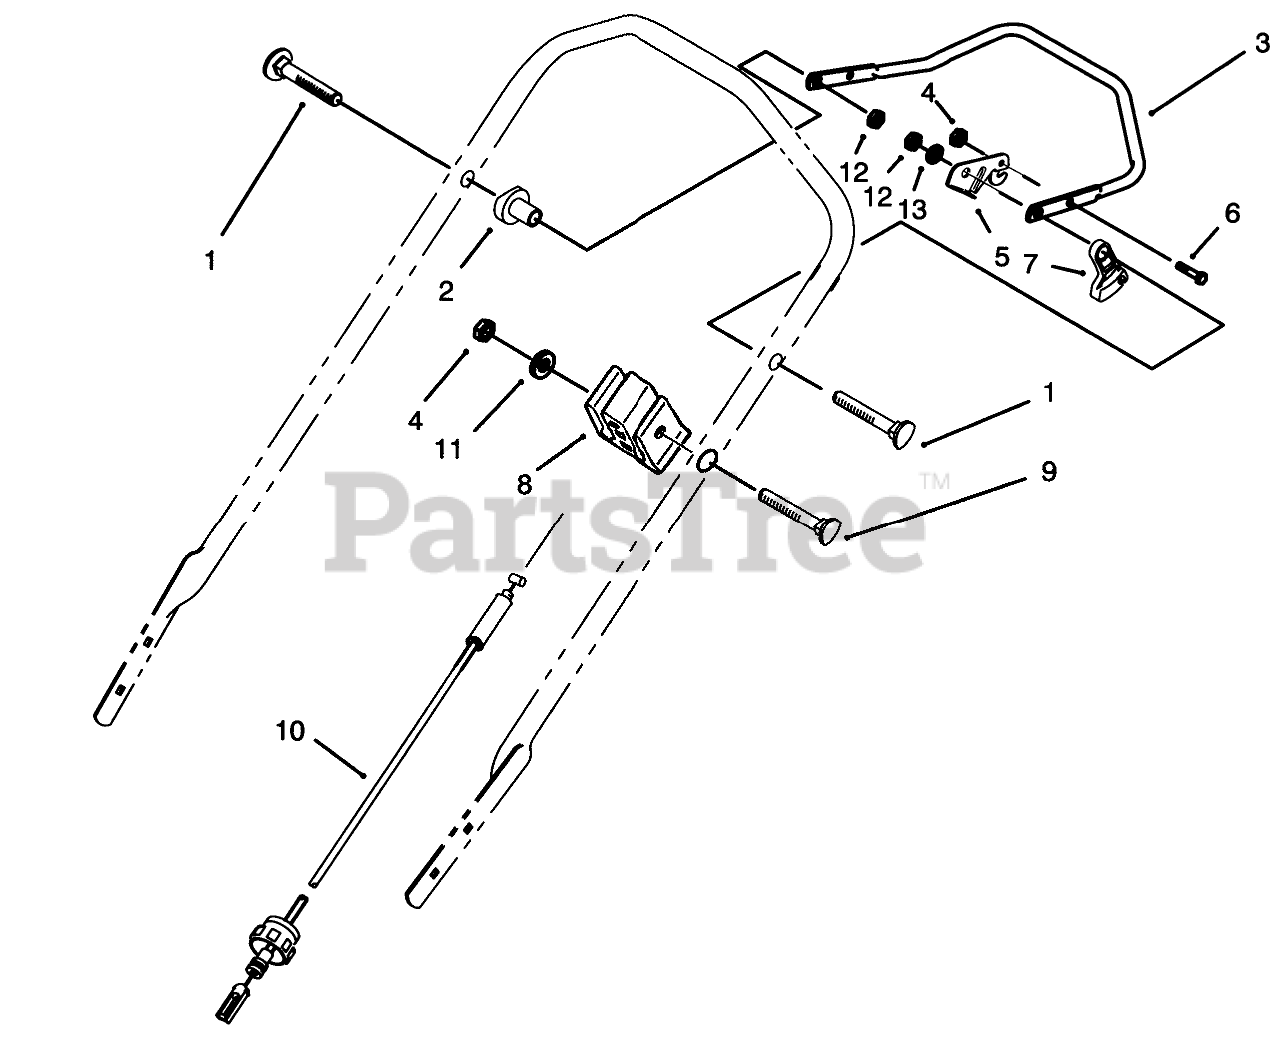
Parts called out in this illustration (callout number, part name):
1	SCREW-HANDLE
2	SPACER-SUPPORT
3	Bar-Control
4	NUT-LOCK, NI
5	CONTROL LEVER
6	SCREW-HH
7	LEVER-TRACTION
8	SUPPORT-CABLE
9	SCREW-HANDLE
10	TRACTION CABLE
11	WASHER-FLAT
12	NUT-LOCK, NI
13	WASHER-PLAIN
